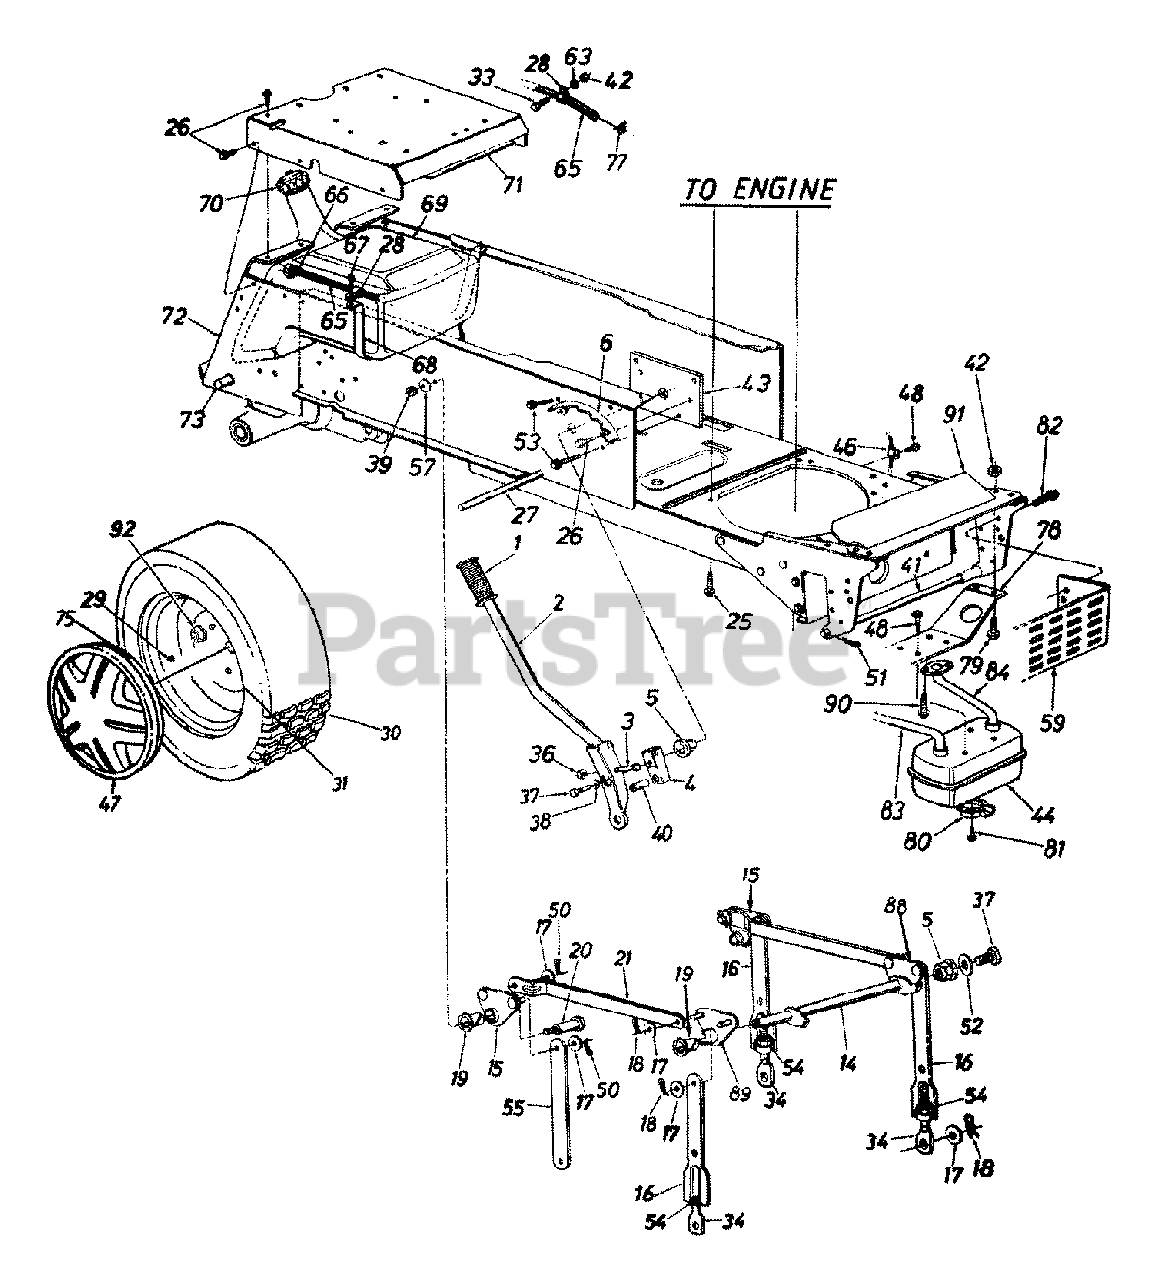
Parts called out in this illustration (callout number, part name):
1	Grip
2	Lift Handle Ass'y.
3	Hex Bolt 5/16-18 x 1.5" Lg.
4	Lift Shaft Drive
5	Plastic Hex Brg. 5/8" I.D.
14	Lift Shaft Ass'y.
15	Lift Pivot Brkt. Ass'y.
17	Fl-Wash. 1/2" I.D. x 1.00" O.D. x .090"
18	Hairpin Cotter
19	Flanged Brg. 5/8" I.D.
20	Shld. Bolt 5/8" Dia. x .96" Lg. 3/8-16
26	Hex Thd. Rolling Scr. 5/16-18 x .75" Lg.
27	Running Board Rod
29	Air Valve
33	Hex Bolt 1/4-20 x .62" Lg.
34	Eye Bolt Adj. Link 1/2-13 Thd.
36	Hex Cent. L-Nut 5/16-18 Thd.
37	Hex Bolt 5/16-24 x .75" Lg. (Gr. 5)
39	Hex Top L-Nut 3/8-16 Thd.
40	Compression Spring
41	Deck Connecting Rod
42	Hex Sems Nut 1/4-20 Thd.
46	Mounting Clamp
47	Hub Cap
48	Hex Wash. Hd. TT-Tap Scr. 1/4-20 x .5" Lg.
50	Cotter Pin .09 Dia. x 1.0" Lg.
51	Int. Cotter Pin
52	Flat Wash. .34" I.D. x 1.12" O.D. x .125"
53	Hex Wash. Hd. AB-Tap Scr. 5/16-18 x .5" Lg.
54	Hex Nut 1/2-13 Thd.
57	Bell-Wash. .4" I.D. x 1.13" O.D.
65	Fuel Line 46" Lg.
67	Hex AB-Tap Scr. 1/4 x .62" Lg.
68	Fuel Tank Strap
71	Seat Plate
75	Spring Clip
78	Muffler Mounting Brkt.
79	Hex Bolt 1/4-20 x .62" Lg.
80	Muffler Deflector
81	Hex Wash. Hd. F-Tap Scr. #8 x .32" Lg.
82	Hex Wash. Hd. TT-Tap Scr. 5/16"-18 x .62" Lg.
83	Exhaust Tube - R.H.
84	Exhaust Tube - L.H.
88	Lift Pivot Brkt. - L.H.
89	Lift Pivot Brkt. - R.H.
90	Socket Scr. M8 x 1.25" x 20MM Lg.
91	Heat Shield
92	Lug Nut 7/16-14 Thd.
